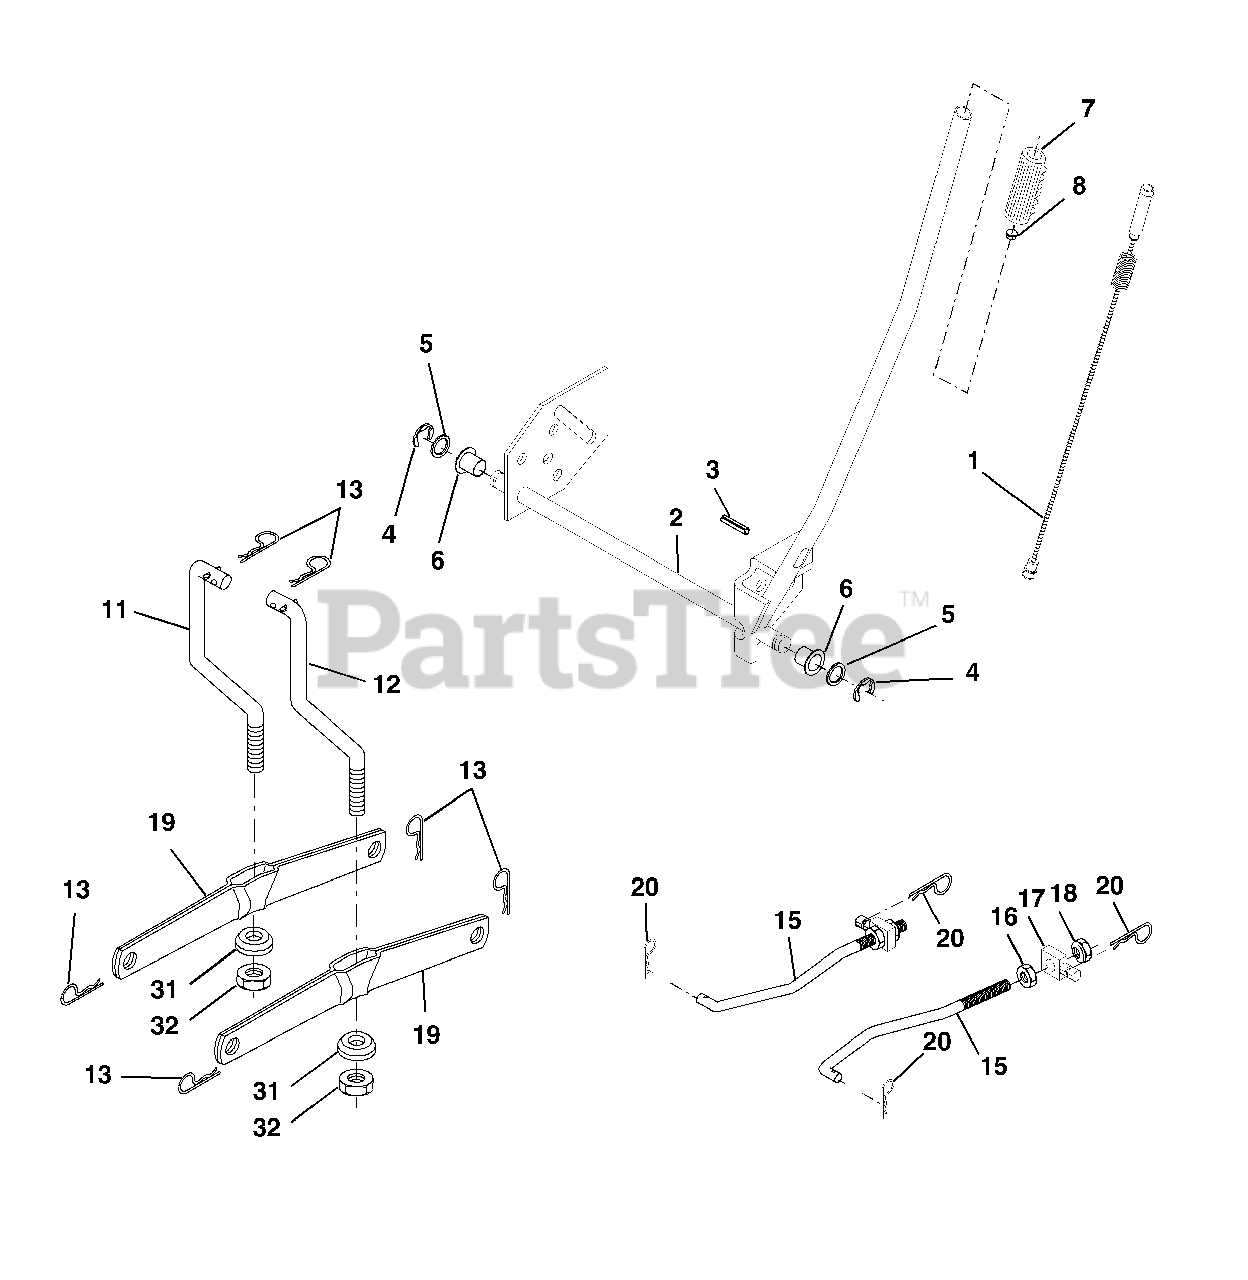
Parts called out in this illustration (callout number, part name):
1	Wire Asm Inner/Sprg w/Plunger
2	Shaft Asm Lift
3	Pin Groove
4	E Ring #5133-62
5	Washer 21/32 x 1 x 21 Ga.
6	Bearing Nylon
7	Grip Handle
8	Button Plunger
11	Link Lift Lh
12	Link Lift Rh
13	Retainer Spring
15	Link Front
16	Nut Jam Hex 1/2-13 Unc
17	Trunnion Blk Zinc
18	Nut Lock w/Wsh 1/2-13 Unc
19	Arm Suspension Rear
20	Retainer Spring
31	Bearing Pvt Lift Spherical
32	Nut Crownlock 3/8-24
